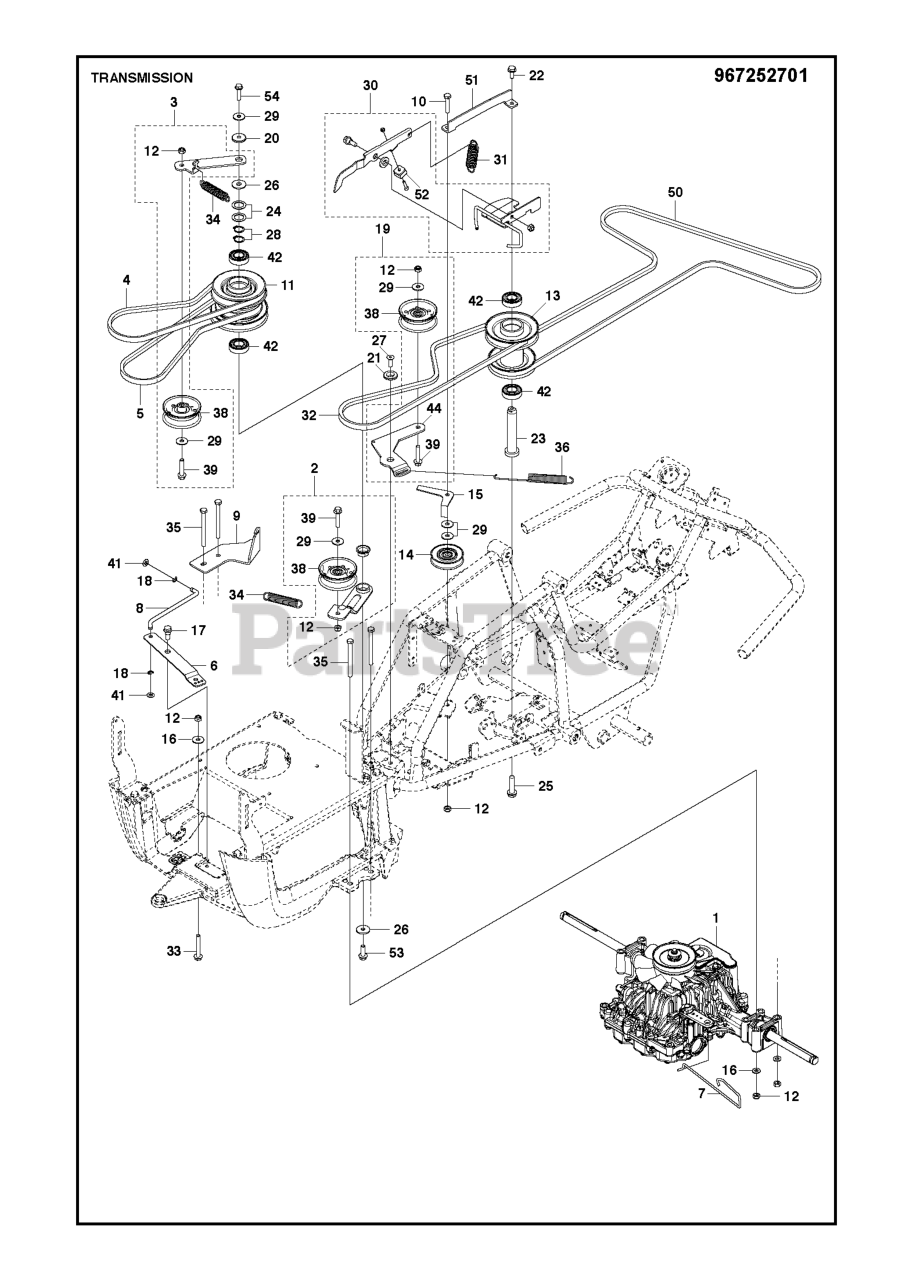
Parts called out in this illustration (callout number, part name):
1	TRANSMISSION T36P HYDROSTATIC
2	BELT TENSIONER ASSY
3	BELT TENSIONER ASSY
12	LOCKNUT M8
16	WASHER BRB 8.4X17
19	BELT TENSIONER
20	WASHER
28	RETAINING RING SGA 20
30	BRAKE ASSY
32	BELT INTERMEDIATE 42 SD
33	SCREW EHHFM
38	IDLER PULLEY
42	BALL BEARING 6004-2RS1
44	BELT TENSIONER
54	BOLT
